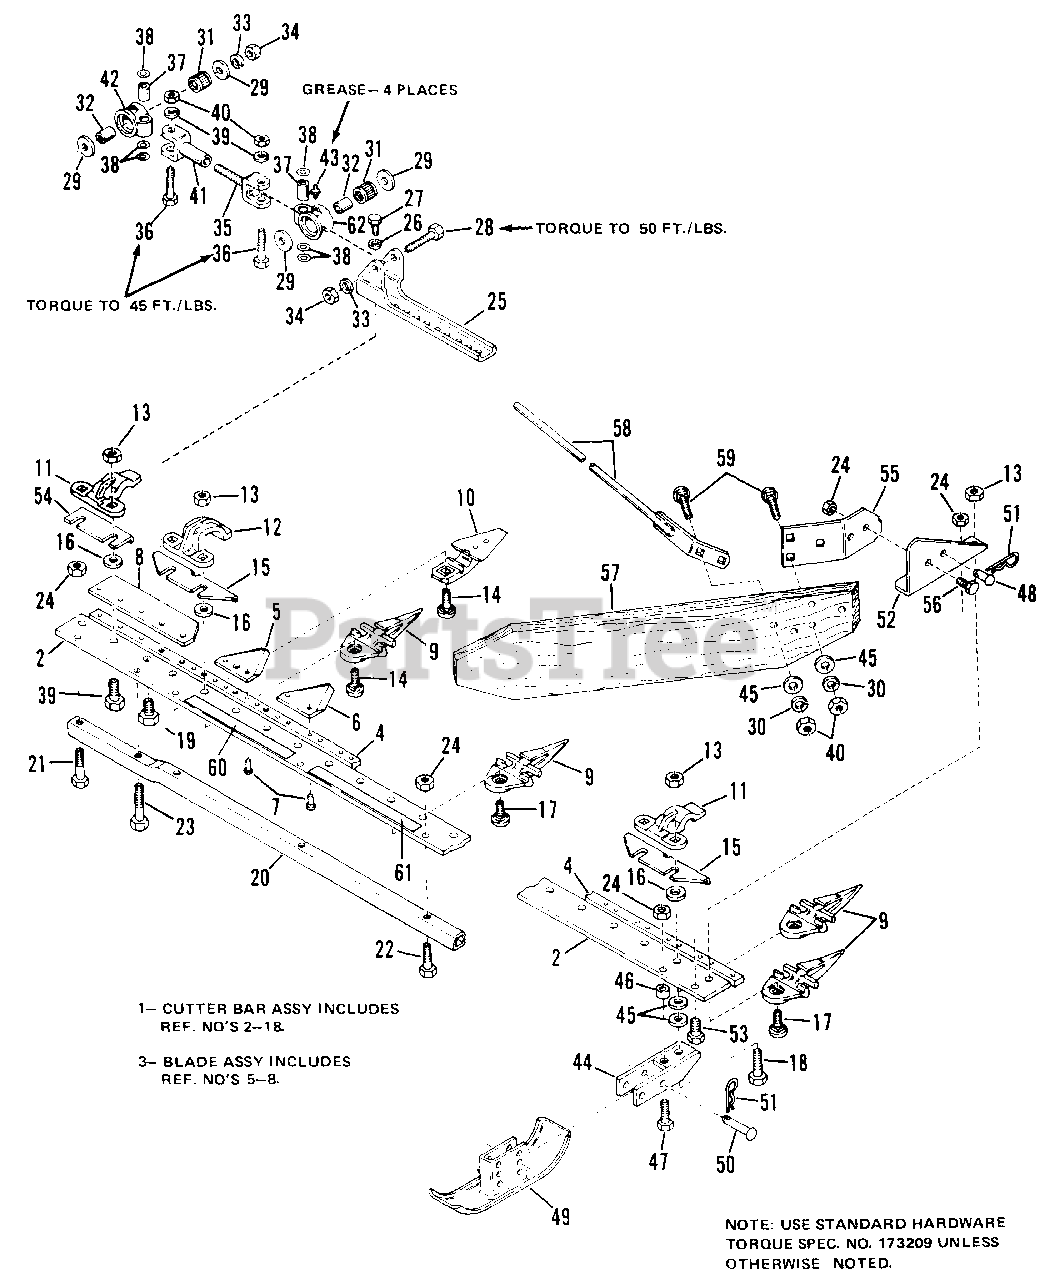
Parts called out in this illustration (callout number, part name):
1	BAR ASSY, Cutter, (Includes Ref. No's 2-18)
2	BAR, Cutter
3	BLADE ASSY, (Includes Ref. No's 5-8)
5	SECTION, Knife
6	SECTION, Knife
7	RIVET, Oval Hd., No. 5-1/2 x 21/32
8	BAR, Filler
10	FINGER ASSY, Shear
11	CLIP, Bar
12	CLIP, Bar
13	NUT, Hex, Lock, 7/16-14
14	BOLT, Rd. Hd., Sq. Nk., 7/16-14 x 1-1/2
15	PLATE, Wear
16	WASHER, Plain
17	BOLT, Rd. Hd., Sq. Nk., 7/16-14 x 1-1/4
18	CAPSCREW, Hex Hd., 7/16-14 x 1-1/2
19	CAPSCREW, Hex Hd., 5/16-18 x 1
20	TUBE, Square
21	CAPSCREW, Hex Hd., 3/8-16 x 2-1/4
22	CAPSCREW, Hex Hd., 7/16-14 x 2
23	CAPSCREW, Hex Hd., 7/6 7/16-14 x 1/4
24	NUT, Hex, Full Lock, 3/8-16
25	HEAD, Sickle
26	LOCKWASHER, Spring, 5/16
27	CAPSCREW, Hex Hd., 5/16-24 x 3/4
28	CAPSCREW, Hex Hd., 7/16-14 x 2-1/4
30	LOCKWASHER, Spring, 3/8
31	BEARING, Needle
33	LOCKWASHER, Spring, 7/16
34	NUT, Hex, 7/16-14
35	CLEVIS ASSY
36	CAPSCREW, Hex Hd., 3/8-16 x 2-1/4, Gr. 8
37	BEARING, Pivot Block
39	CAPSCREW, Hex Hd., 7/16-14 x 1-1/2
40	NUT, Hex, 3/8-16
41	CLEVIS ASSY
42	HOUSING, Bearing Pitman
43	FITTING, Lube, 1/4-28
44	SUPPORT ASSY
45	WASHER, Plain, 3/8
47	CAPSCREW, Hex Hd., 3/8-16 x 1-1/2
49	SHOE ASSY
51	CLIP, Spring
53	CAPSCREW, Hex Hd., 3/8-16 x 1
54	PLATE, Wear
55	SUPPORT, Div. Brd.
56	BOLT, Hex, Shoulder
57	BOARD, Divider
58	ROD ASSY, Divider
59	BOLT, Rd. Hd., Sq. Nk., 3/8-16 x 1-1/2
60	DECAL, Safety First
61	DECAL, Engine Shut-off
62	HOUSING, Bearing Pitman
